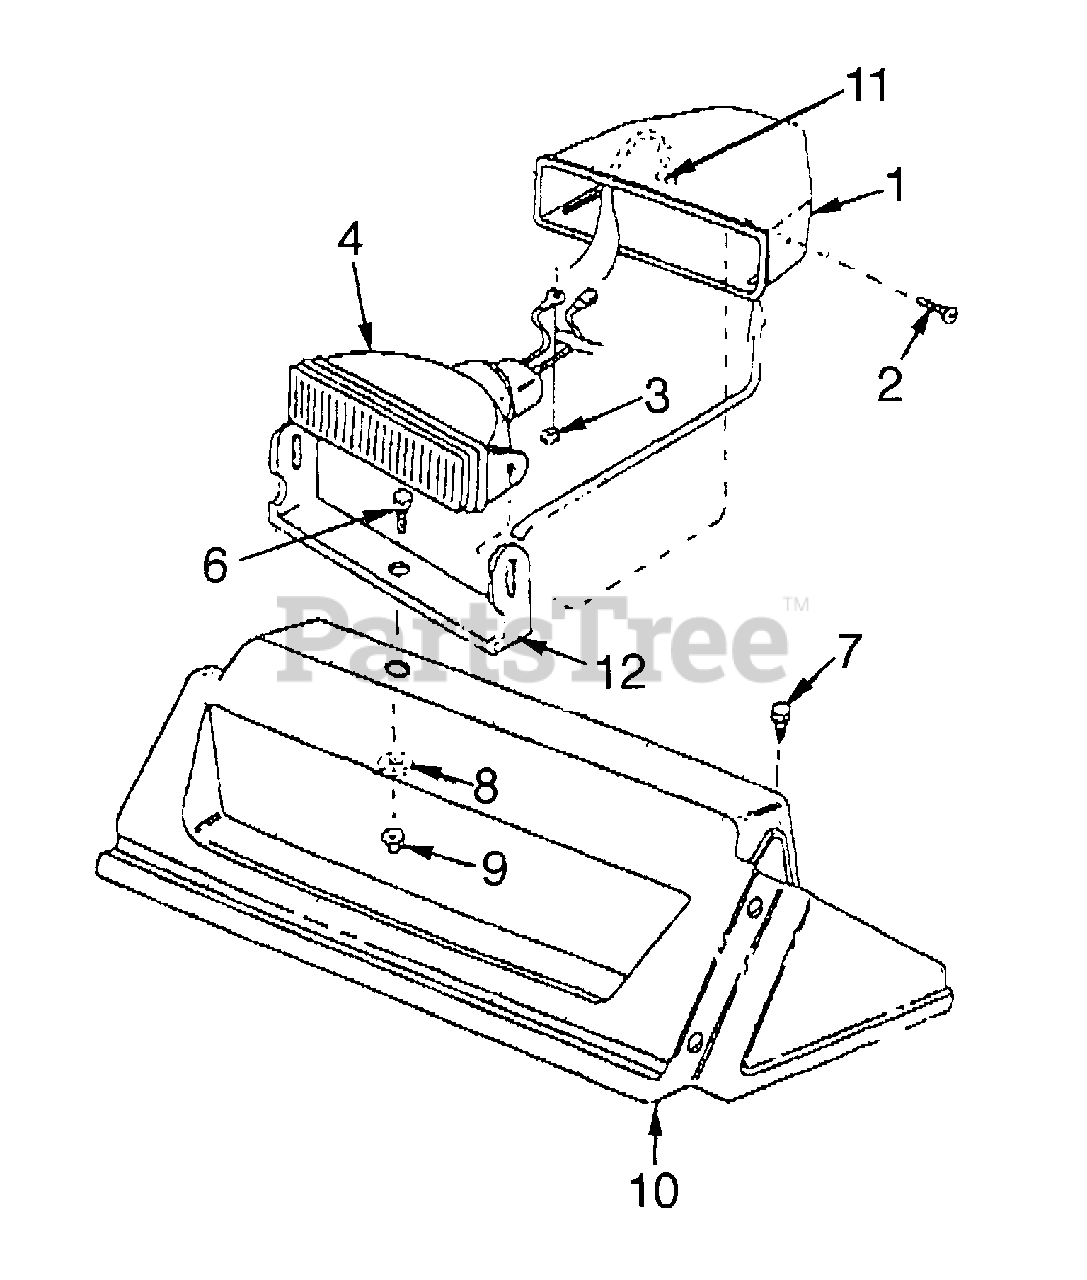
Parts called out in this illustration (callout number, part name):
1	Halogen Lamp Housing
2	Phillips Pan Head Screw M 4 x 16
3	Hex Sems Nut 1/4-20
4	Lamp/Lens Housing Ass'y
4	Halogen Light Wire Harness
4	#890 Halogen Bulb
6	Carriage Bolt 5/16-18 x .75
7	Pan Head B-Tapp Screw #10
8	Fl-Wash .344 ID x .88 OD
9	Hex Ins L-Nut 5/16-18
10	Handle Panel
11	Grommet .38 ID x .50 OD x 12
12	Lamp Mounting Bracket
